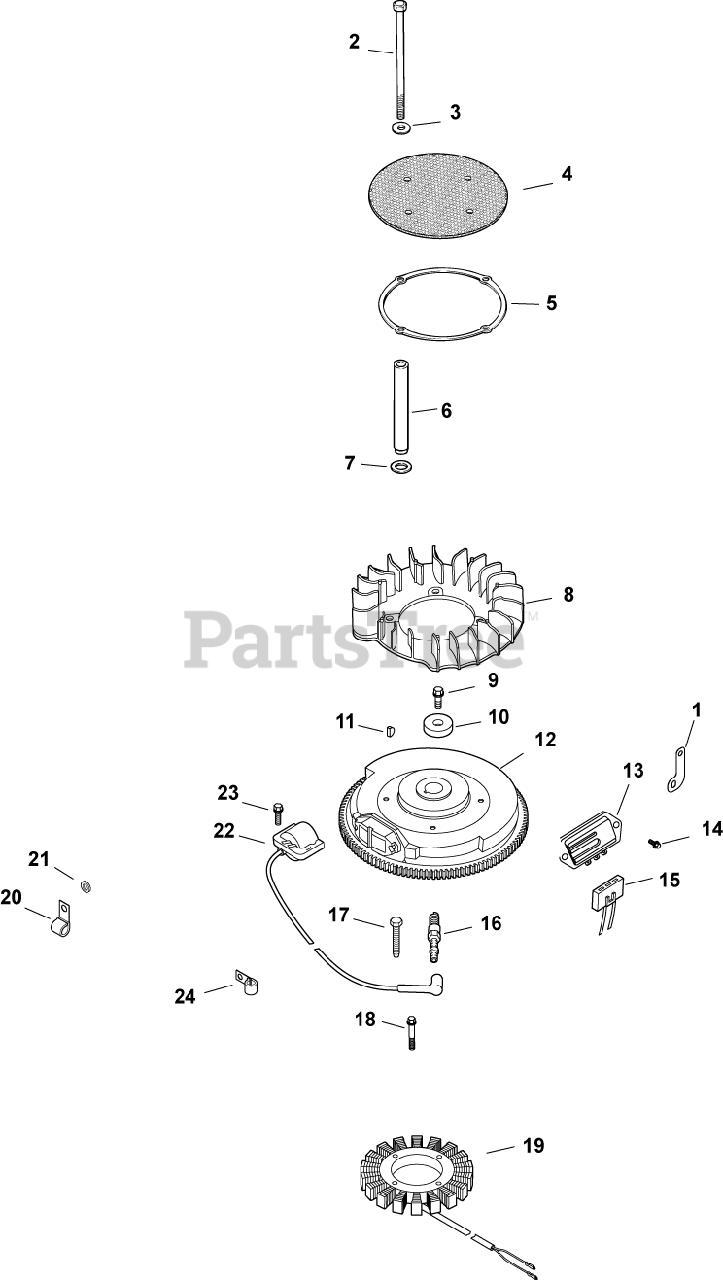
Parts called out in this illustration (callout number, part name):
1	BRACKET, GROUND STRAP USE 24 518 12-S
2	SCREW, CAP M6X1.0X99.5
3	WASHER, FLAT 1/4" (O.D. 5/8")
4	SCREEN, GRASS
5	RING, SUPPORT USE 25 141 08-S
7	WASHER, SPRING 10 MM
9	SCREW, FLG M10X1.5X45 - (#25086361S)
10	WASHER, FLAT 13/32"
11	KEY, 3/16" X 5/8"
12	FLYWHEEL ASSEMBLY (LW)
13	REGULATOR/RECTIFIER
14	SCREW, HEX FLANGE HI-LO
15	CONNECTOR
16	SPARK PLUG, RFI
17	SCREW, M5X0.8X25 - (#25086402S)
18	SCREW, SKT SET #10-24X1/4"
19	KIT, 15 / 20 AMP STATOR
20	CLIP, CABLE
21	WASHER, FLAT 1/4" (O.D. 1/2")
22	MODULE, SPARK ADV (DSAI)-USE 24 584 89-S
23	SCREW, FLG THD FRM M5X.8X20-(#25086399S)
